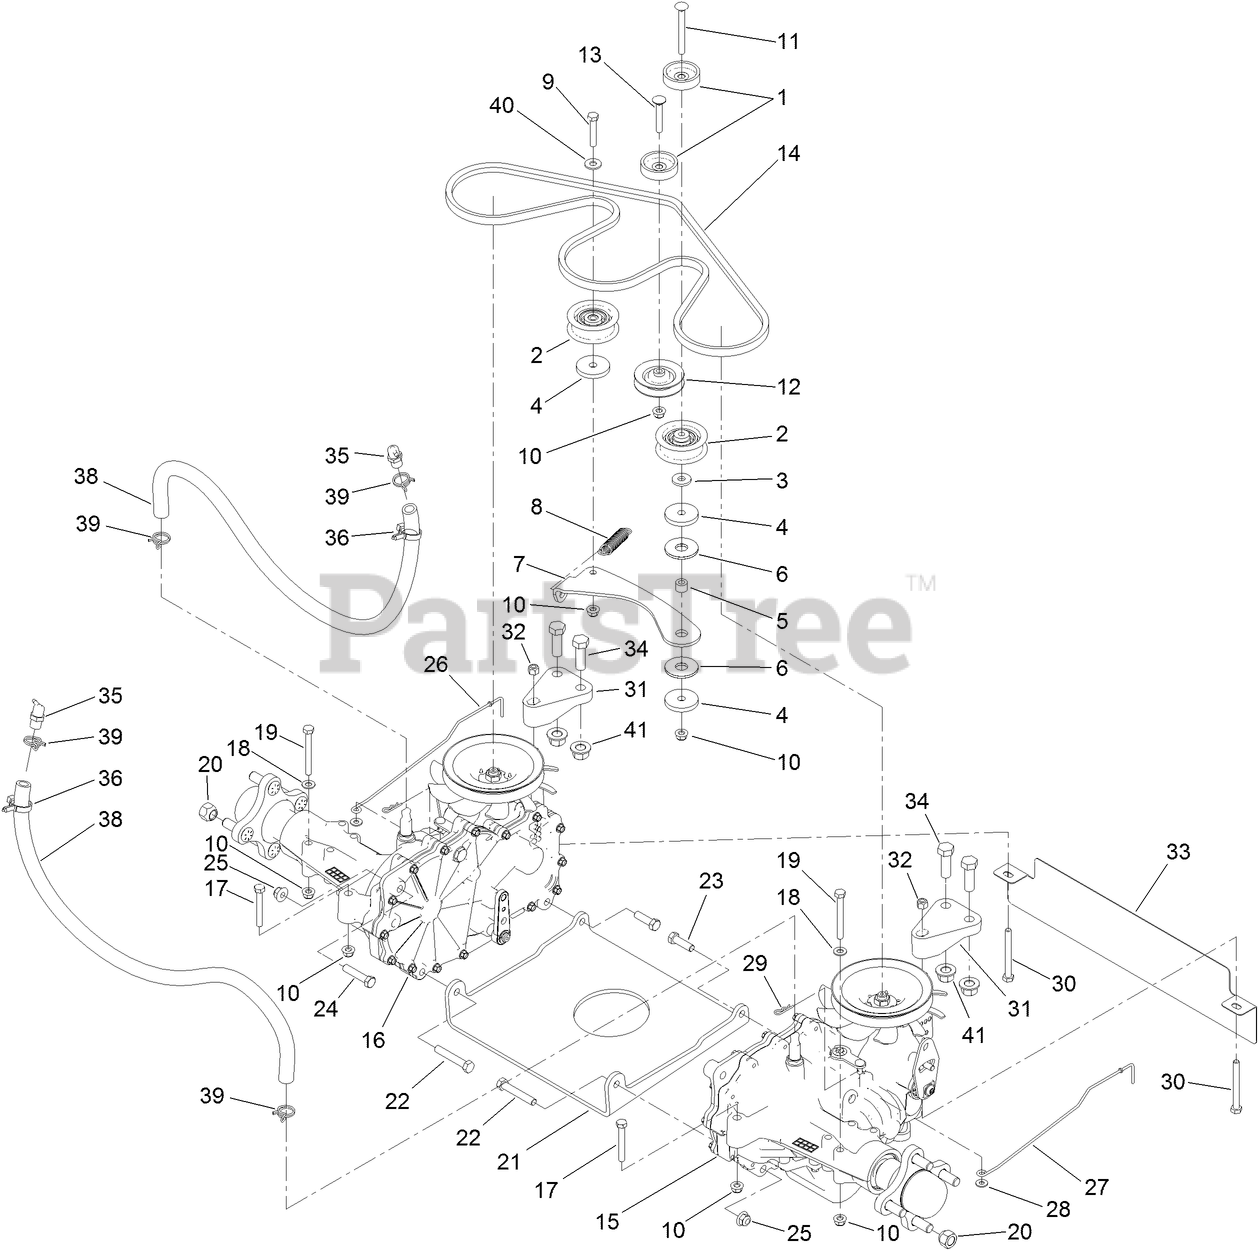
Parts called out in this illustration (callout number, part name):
1	SPACER
2	PULLEY-IDLER
3	WASHER
4	WASHER-PLAIN
5	BUSHING
6	WASHER-FRICTION, COMPOSITE
7	ARM-IDLER
8	SPRING-RETURN, PEDAL
9	SCREW-HH
10	NUT-HF, NI
11	SCREW-CARR
12	PULLEY-IDLER
13	BOLT-CARR
14	V-BELT
15	LH HYDRO TRANSMISSION ASM
16	RH HYDRO TRANSMISSION ASM
17	SCREW-HH
18	WASHER-PLAIN
19	SCREW-HH
20	NUT-LUG
21	PLATE-CROSS, HYDRO
22	SCREW-HH
23	SCREW-HH
24	SCREW-HH
25	NUT-HF, NI
26	ROD BYPASS, RH
27	ROD BYPASS, LH
28	WASHER-FLAT
30	SCREW-HH
31	SUPPORT-HYDRO, REAR
32	NUT-LOCK, NI
33	GUARD REAR, WIDE
34	SCREW-HH
35	BREATHER KIT
36	CLAMP-HOSE
38	HOSE-HYDRO
39	CLAMP-HOSE
40	WASHER-FLAT
41	NUT-LOCK
